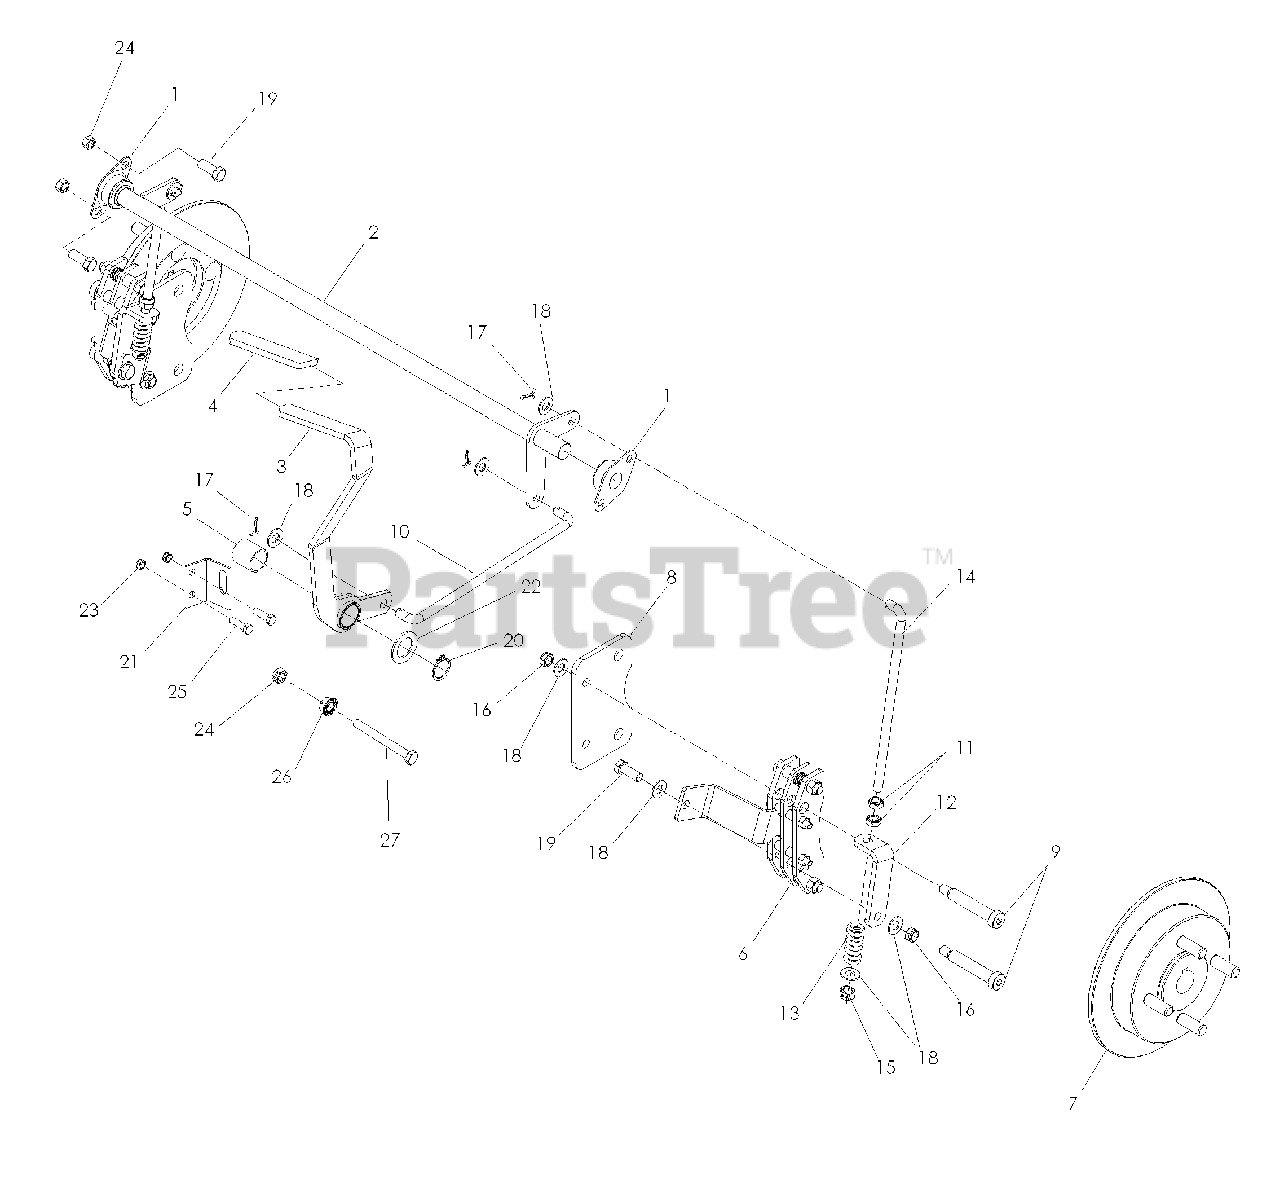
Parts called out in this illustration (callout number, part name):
1	BUSHING, FLANGED
2	BRAKE CROSS SHAFT
3	BRAKE LEVER
4	GRIP PARK BRAKE
8	PLATE, BRAKE
9	SCREW, 3/8 -16 x 2 1/2, SKT
10	LINKAGE, BRAKE
11	NUT, 3/8 -24, JAM
14	LINKAGE, REAR BRAKE
15	NUT, 3/8 -24, CENTERLOCK
16	NUT, 3/8 -16, THIN NYLOC
17	PIN COTTER, 3/32 x 3/4
18	WASHER, 3/8, SAE
19	HCS 3/8-16 x 1
20	RING, RETAINING, EXT 7/8
23	NUT 1/4-20 HEX NYLOC
24	NUT 3/8-16 HEX NYLOC
25	HCS, 1/4 -20 x 3/4
26	NUT, 3/8 -16, WHIZLK
27	HCS, 3/8 -16 x 2 1/2
